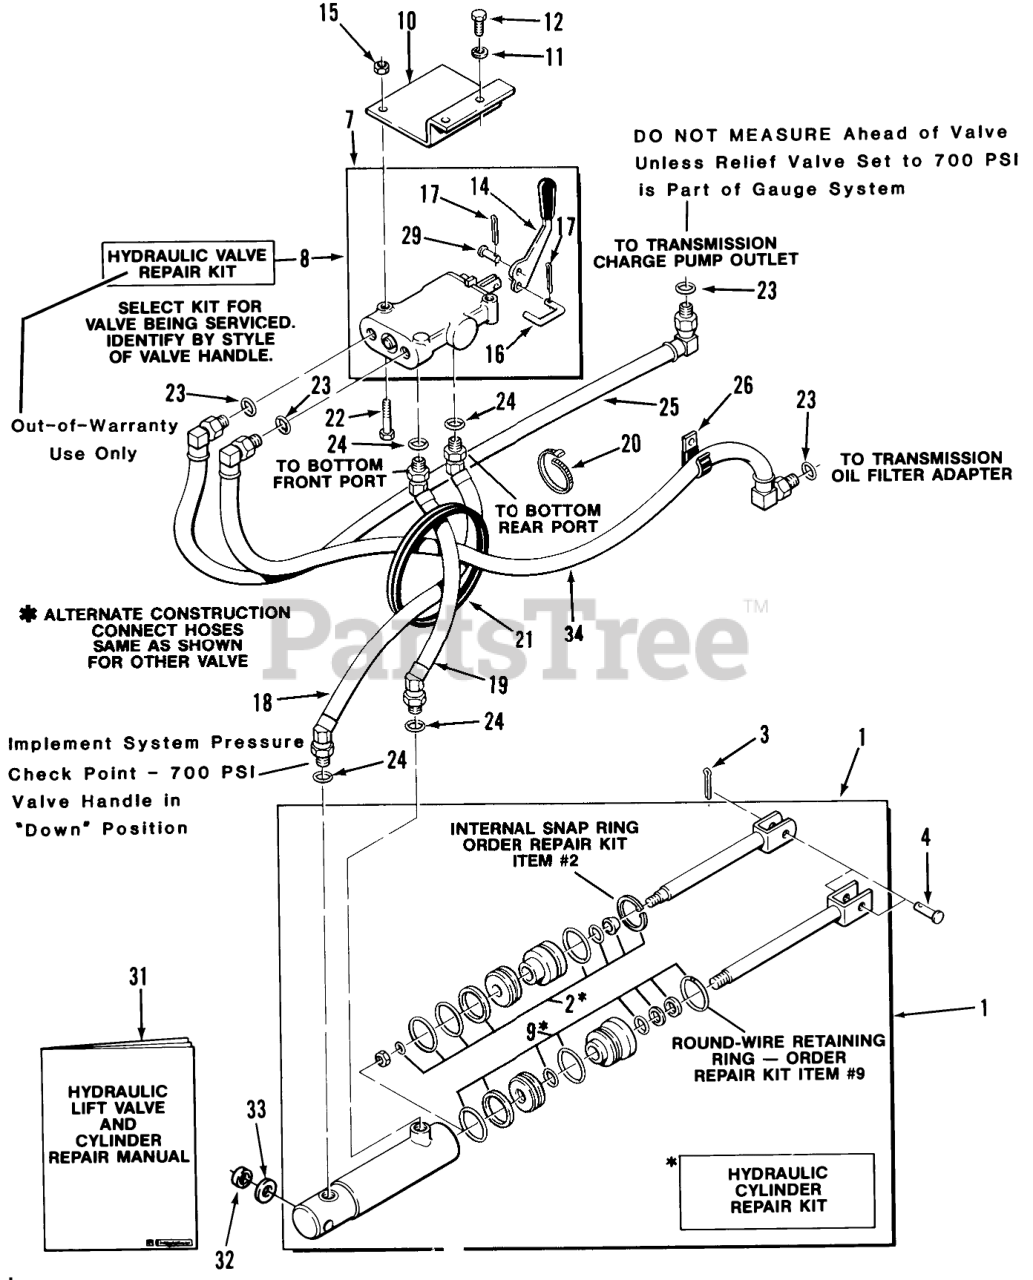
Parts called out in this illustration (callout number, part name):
1	CYLINDER
2	S/A O-RING&GASKET AS
4	CLEVIS PIN
7	Hydraulic Valve
8	S/A 110068 VALVE
9	S/A 108872 HYD CYL
10	ASSY VALVE SUPPOR B
11	Lockwasher
12	Bolt
14	VALVE HANDLE
15	Nut
16	C-HOOK
17	Cotter Pin
18	Hose ASM-Hydraulic
19	Hose ASM-Hydraulic
20	PLASTIC TIE
21	GROMMET
22	Screw-Hex. Hd.
23	0-Ring
24	O RING
25	ASSY HOSE HYDRAULIC
26	CLIP
29	Pin
31	Repair Manual
32	Spacer
33	WASHER
34	ASSY HYD HOSE
